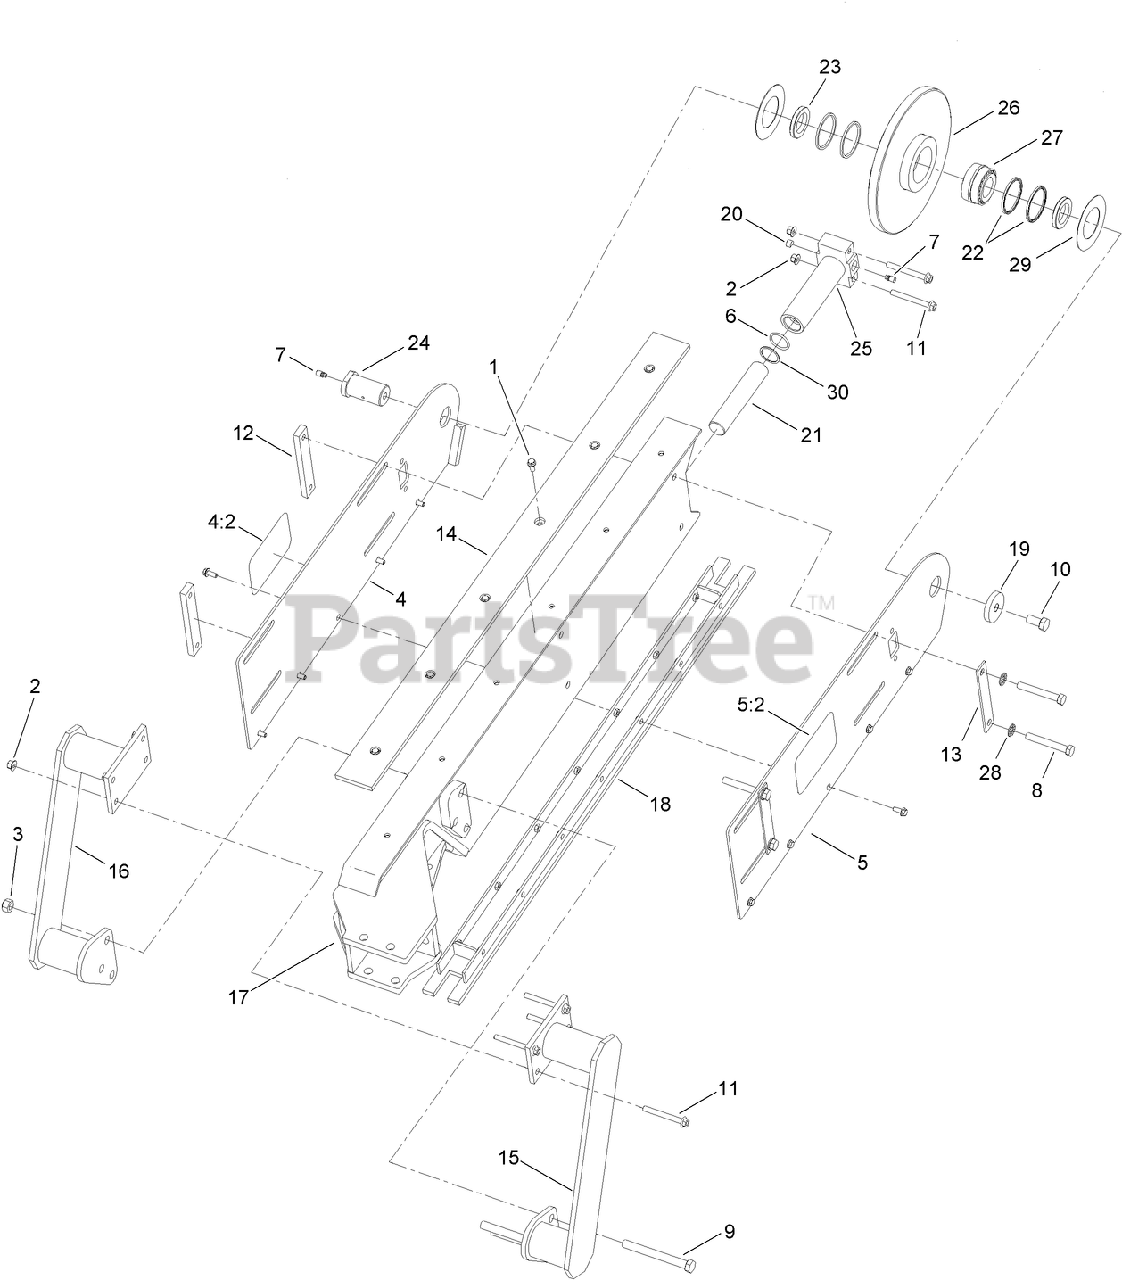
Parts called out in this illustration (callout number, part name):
1	SCREW-HHF
2	NUT-LOCK, HHF
3	NUT-LOCK
4	RH BOOM END PLATE ASM
5	LH BOOM END PLATE ASM
7	FITTING-LUBE, STRAIGHT
11	BOLT-HHF
12	BAR-TAPPED
13	BAR-CLAMP
14	BAR-WEAR PAD, UPPER
15	MOUNT-CRUMBER, LH (ROCK)
16	MOUNT-CRUMBER, RH (ROCK)
17	BOOM-ROCK, 60IN
18	CHANNEL-WEAR PAD, 4IN
20	PLUG-BLEED
21	ROD-BOOM, END (CYLINDER)
22	SEAL-ROLLER
23	SPACER-bearing
24	PIN-BOOM
25	BOOM END CYLINDER ASM
26	ROLLER-BOOM END
27	BEARING KIT
28	WASHER-LOCK
29	WASHER-BOOM, END (ROLLER)
30	WASHER-BACKUP
